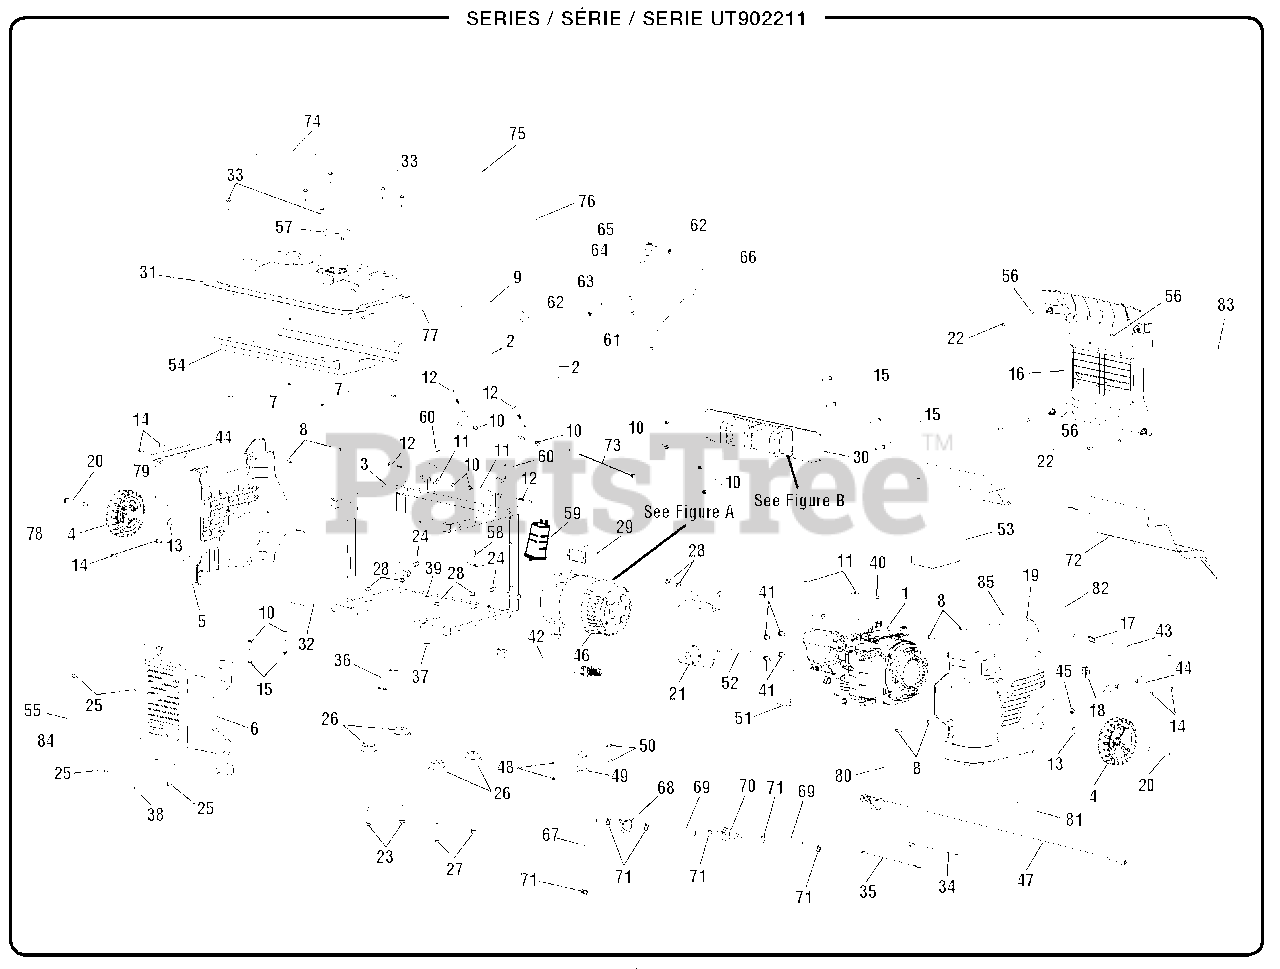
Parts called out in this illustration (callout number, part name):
2	Handle Warning Label
3	Frame Assembly
5	Panel Cover
6	Service Panel
7	Nylon Washer (D20 x D8 x 4.5t)
8	Screw (#9-18 x 20 mm)
9	Handle Assembly
10	Lock Nut (1/4-20 in.)
11	Washer (1/4 in.)
12	Bolt (1/4-20 x 2 in., Hex Hd.)
13	Washer (1/2 in.)
14	Screw (12-14 x 15 mm)
15	Screw (1/4-20 x 1-3/4 in., T30 Torx Hd.)
16	Control Panel Cover
17	Release Pin
19	Outer Panel
20	Wheel Axle
21	Muffler Assembly
22	Screw (#9-18 x 15 mm)
23	Bolt (M8 x 45 mm, Flange Hd.)
24	Axle Clip
25	Screw (1/4-20 x 1/2 in.)
26	Rubber Foot
27	Bolt (M8 x 50 mm)
28	Lock Nut (M8)
29	Capacitor
30	Control Panel Assembly
31	Fuel Tank Assembly
32	Intake Heat Shield
33	Screw (#10-16 x 1 in.)
34	White Assembly Wire (18 Ga)
35	Brown Wire Assemly (18 Ga)
36	Ground Assembly Wire
37	Flange Nut (15/16-18)
38	Emissions Label
39	Bolt (5/16-18 x 3/4 in.)
40	Bolt (M6 x 10 mm)
41	Bolt (5/16-24 x 5/8 in.)
42	Pigtail (Male Connector w/ Wire)
43	Lanyard (3/16 in.)
44	Handle Grip
45	Recoil Rope Guide
46	Generator Head Assembly
47	Battery Cable Assembly
48	Hex Nut (M5)
49	Capacitor Holder
50	Bolt (M5 x 16 mm, Pan Hd.)
51	Heat Shield (Engine Air Inlet)
52	Heat Shield (Separator)
53	Heat Shield (Surround Muffler)
54	Heat Shield (Under Fuel Tank)
55	Engine Lubricant Label
57	Fuel Tank Cap
58	Canister Bracket
61	Fuel Line Clamp (3/8 in.)
62	Fuel Line Clamp (5/16 in.)
63	Fuel Line Hose (4 mm, 305 mm)
65	Fuel Check Valve
66	Fuel Line Hose (5 mm, 432 mm)
67	Fuel Hose (150 mm)
68	Fuel Shut-off Valve
69	Fuel Hose (100 mm)
70	Fuel Line Filter
71	Fuel Line Clamp (1/2 in.)
72	Heat Shield
73	Cable Tie (18.6 in.)
74	CPSC Label
75	Engine Hang Tag
76	Danger Label
77	Fire Danger Label
78	Ground Warning Label
79	Hot Surface Label
80	Starting Instructions Label
81	Data Plate
82	Engine Switch Label
83	Logo Label
84	Combustion Label
85	Fuel Valve Label
